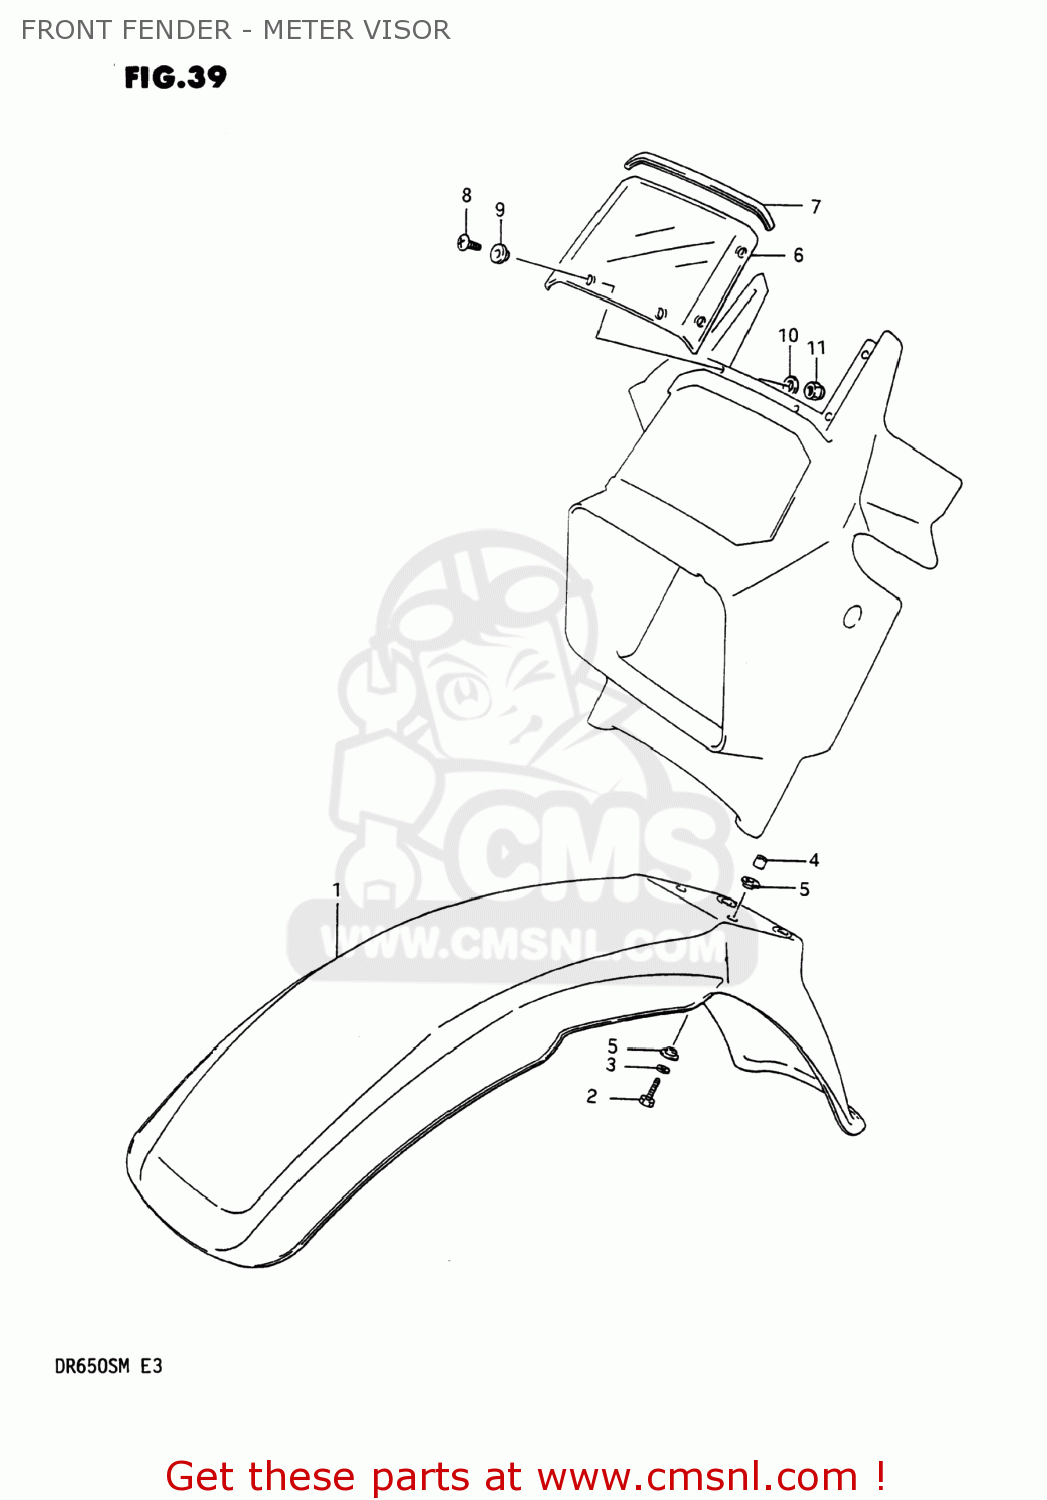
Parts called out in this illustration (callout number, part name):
1	FENDER,FRONT
2	BOLT
3	WASHER,LOCK
4	SPACER(6.1X9X7.5)
5	WASHER
6	VISOR,METER
7	MOLDING
8	SCREW 5X10
9	CUSHION
10	WASHER,5MM
11	NUT
